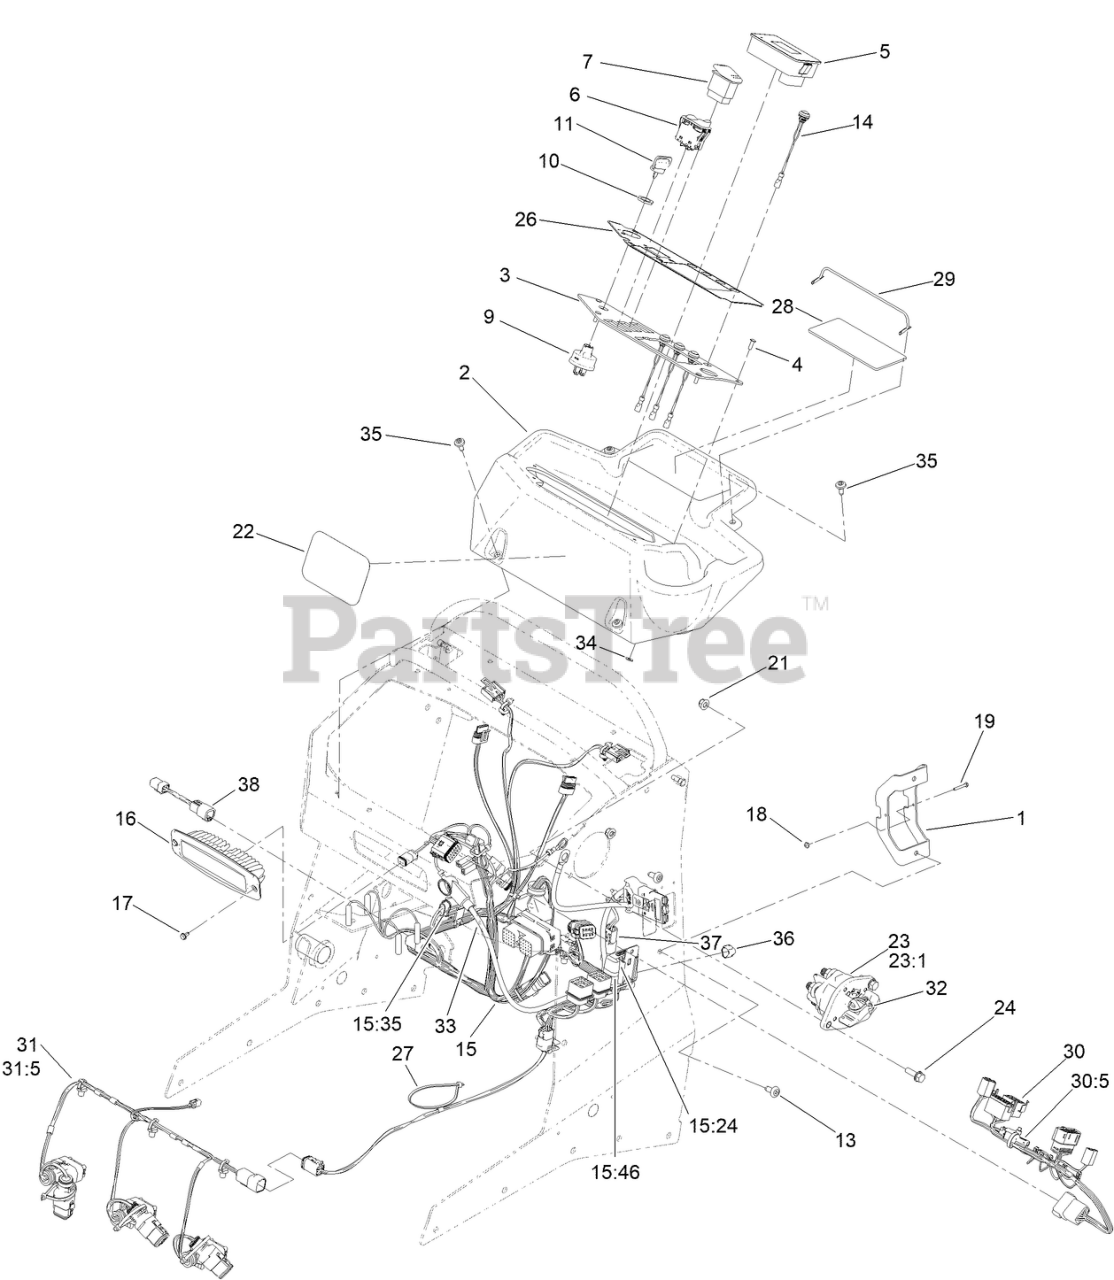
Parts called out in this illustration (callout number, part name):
1	BRACKET-CHARGER, DUAL
2	DASH-CONTROL PANEL
3	PLATE-CONTROL PANEL
4	RIVET-POP
5	TDM 2002
6	SWITCH-ROCKER, (ON)-ON-OFF
7	SWITCH
9	SWITCH-KEY, SPST
11	KEY-IGNITION
14	SWITCH-PUSHBUTTON
15	HARNESS-WIRE, MAIN
15:24	FUSE-MINI BLADE, 2 AMP
15:35	FUSE-BLADE, 10A
15:46	FUSE-MINI BLADE, 7.5 AMP
16	MOUNT-FLUSH, LIGHT
17	SCREW-HWH
18	NUT-HEX
19	SCREW
21	NUT-HF, NI
22	DECAL
23	SWITCH-DISCONNECT
23:1	NUT-HF
24	SCREW-HHF
26	DECAL-PANEL, CONTROL
27	TIE-CABLE
28	PAD-RUBBER, W/ADHESIVE
29	STRAP-ELASTIC
30	HARNESS-WIRE, CONTROL PANEL
30:5	RESISTOR-120 OHM
31	HARNESS-WIRE, DECK
31:5	RESISTOR-120 OHM
32	TIE-CABLE
33	HARNESS-WIRE, CHARGER PORT
34	WASHER-PLAIN
35	SCREW-SHOULDER
36	CAP-PLUG, 3 WAY
37	FERRITE-SNAP ON
38	HARNESS-WIRE, JUMPER
